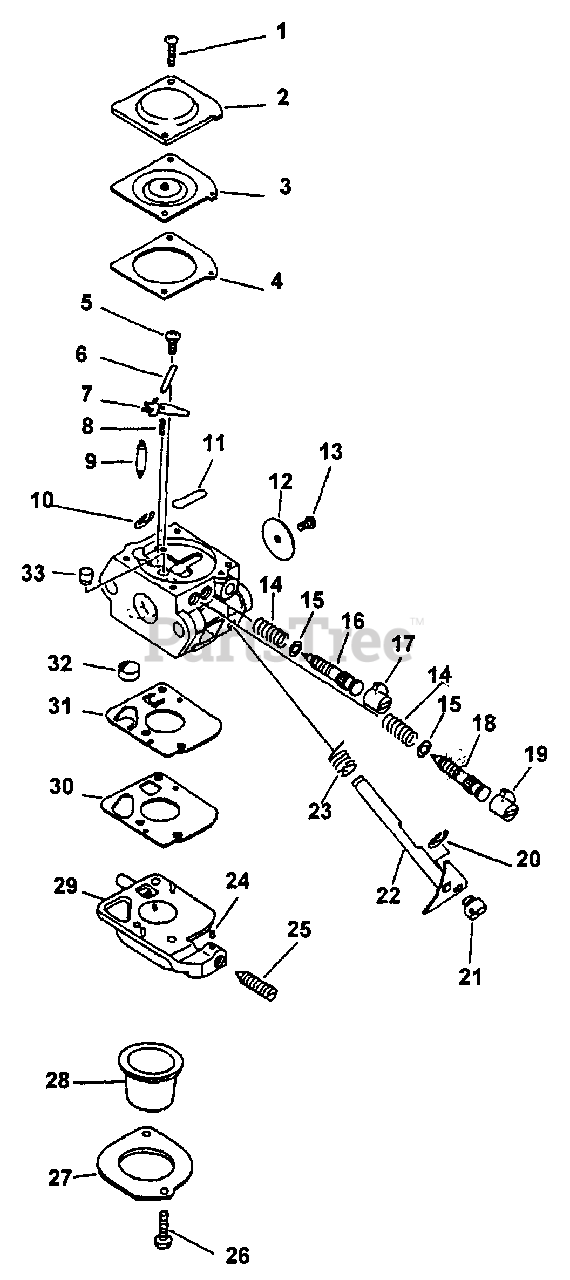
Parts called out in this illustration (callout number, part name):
2	COVER, METERING DIAPHRAGM
3	DIAPHRAGM, METERING
4	GASKET, METERING
6	PIN, METERING LEVER
7	LEVER, METERING
8	SPRING, METERING LEVER
9	VALVE, INLET NEEDLE
11	PLUG, WELCH
12	VALVE, THROTTLE
14	SPRING, NEEDLE
16	NEEDLE, IDLE
17	CAP, LIMITER
18	NEEDLE, HIGH SPEED
19	CAP, LIMITER - RED
22	SHAFT, THROTTLE
23	SPRING, THROTTLE RETURN
24	PIECE, FRICTION
25	SCREW, IDLE ADJUST
27	RETAINER
28	BULB, PURGE
29	BODY ASSY, PURGE
32	STRAINER
33	NOZZLE, CHECK VALVE
